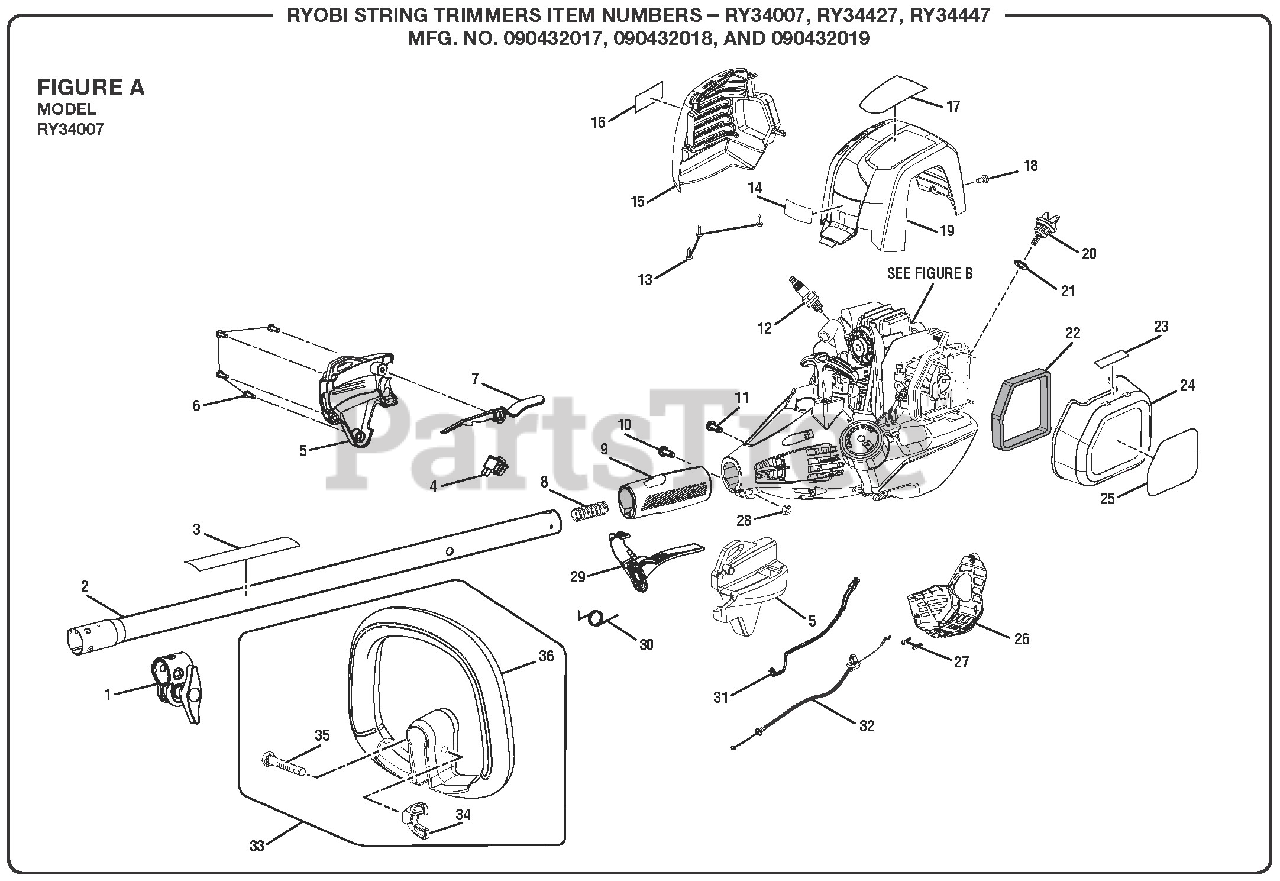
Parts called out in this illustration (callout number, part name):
1	Boom Clamp Assembly
2	Upper Boom Assembly
3	Warning Label
4	Switch (Momentary Contact)
5	Control Handle Assembly
6	Screw (M4 x 20 mm, T20 Torx Pan Hd.)
7	Trigger Lock
8	Compression Spring
9	Rear Handle
10	Bolt (M6 x 20 mm, T27 Torx Button Hd.)
11	Screw (M4 x 8 mm, T25 Torx Pan Hd. T.F.)
12	Spark Plug (Champion RY4C)
13	Screw (M4 x 12 mm, T20 Truss Hd.)
14	Logo Label
15	Muffler Housing
16	Combustion Warning Label
17	X430 Label (RY34007)
18	Shoulder Screw (M4 x 11 mm, T25 Torx Pan Hd.)
19	Top Cover
20	Oil Cap/Dipstick
22	Air Filter
23	Choke Label
24	Air Filter Cover
25	Starting Label
26	Bottom Cover
27	Screw (#6-19 x 1/2 in., Pan Hd. T.F.)
28	Hex Nut (M6)
29	Throttle Trigger
30	Torsion Spring (Throttle Trigger)
31	Lead Assembly
32	Throttle Cable
33	Front Handle Assembly
34	Wing Nut (1/4-20)
35	Screw (1/4-20 x 40 mm, Hex Hd.)
36	Front Handle
